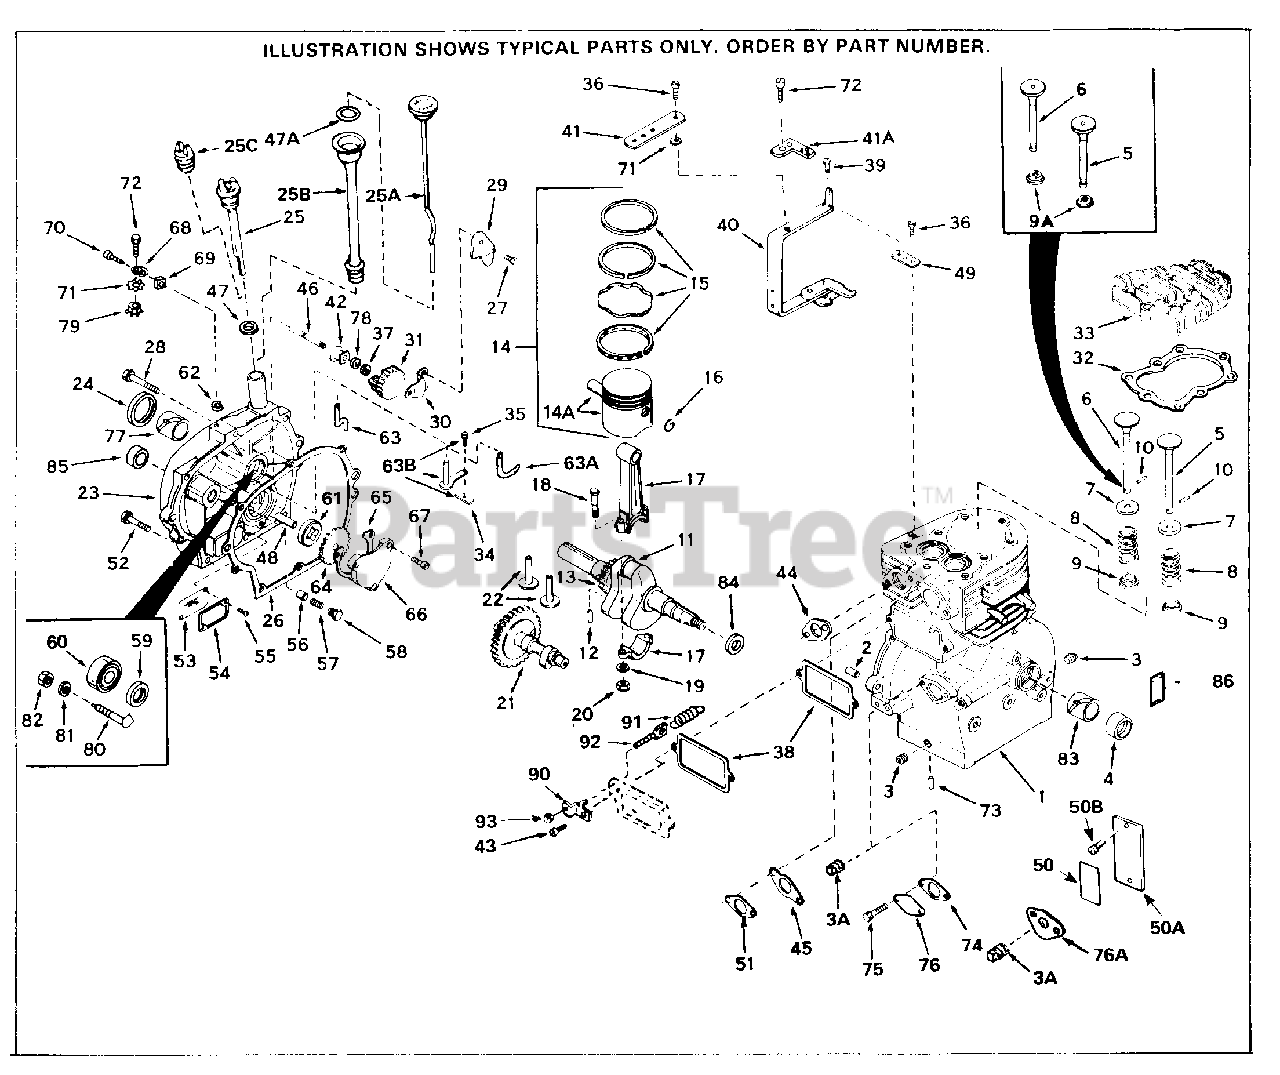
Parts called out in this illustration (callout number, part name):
1	"Cylinder (Incl. 2 thru 5 & 9A) 2-5/8 " Bore
2	Dowel Pin
3	Oil Drain Plug (Sq. hd., 1/4-18)
4	Seal, Oil
5	Intake Valve (Std.) (Incl. 9A)
5	Exhaust Valve (Std.)(Incl. 151)
5	Exhaust Valve (1/32" OS) (Incl. 151)
6	Exhaust Valve (Std.) (Incl. 9A)
6	Exhaust Valve (1/32" OS) (Incl. 9A)
6	Exhaust Valve (Std.)(Incl. 151)
6	Exhaust Valve (1/32" OS) (Incl. 151)
7	Valve Spring Cap
8	Valve Spring
9	Cap, Lower valve spring (Std.)
9	Cap, Lower valve spring (1/32" OS)
10	Pin, Valve spring retaining
11	Crankshaft NOTE: This is a crankless shortblock. Crankshaft was installe din field.
12	Pin, Crankshaft gear only)
13	Crankshaft Gear Early production onl y
14	Piston, Pin & Ring Set (Std.) 2-5/8" Bore
14	Piston, Pin & Ring Set (.010" OS)
14	Piston, Pin & Ring Set (.020" OS)
14A	Piston & Pin Ass'y. (Std.)(2-5/8") In cl. 16
14A	Piston & Pin Ass'y. (.010" OS) Incl. 16
14A	Piston & Pin Ass'y. (.020" OS) Incl. 16
15	Ring Set (Std.) (2-5/8" Bore)
15	Ring Set (.010" OS)
15	Ring Set (.020" OS)
16	Piston Pin Retaining Ring
17	Rod Assy., Connecting (Incl. 18)
18	Connecting Rod Bolt Early production
18	Bolt, Connecting rod Early production
18	Bolt, Connecting rod Late production
19	Washer ion)
20	Nut, Connecting rod Early production
21	Camshaft (MCR)
22	Lifter, Valve
23	Cover, Cylinder (Incl. 24, 46 & 77)
24	Oil Seal equired)
25	Dipstick, Oil (Incl. 47)
26	Gasket, Cylinder cover
27	Screw, 10-25 x 1/2"
28	Screw, 1/4-20 x 1-3/4"
30	Bracket, Governor gear
31	Gear Assy., Governor (Incl. 78)
32	Gasket, Cylinder head
33	Cylinder Head Not included with short block
34	Yoke, Governor
35	Screw, 6-40 x 5/16"
37	Retaining Ring
38	Valve Cover Gasket
39	Rivet, Split Used on early production
40	Governor Lever New lever does not nee d 1 of Ref. No. 39, 68, 71, 72 & 79
42	Spool, Governor
43	Screw, 10-24 x 1/2" (Use as required)
45	Intake Pipe Gasket
47	Oil Fill Plug Gasket
50	Decal, Instruction
50A	Plate, Identification Early producti on
50B	Stud, Drive (Early production)
51	Gasket, Carburetor
52	Screw, 1/4-20 x 1-1/4"
59	Washer, Thrust
60	Bearing, Ball
62	Retaining Ring
63A	Rod, Governor This one piece gov. rod is no longer used. It is replaced by 30699C assy ., Ref. No. 63B
68	Governor Lever Clamp tion)
69	Lock Nut, 10-32
70	Screw, 10-32 x 3/4"
71	Lock Washer #8
72	Screw, 8-32 x 5/16" (Use as required)
73	Pin, Dowel (Use as required)
77	Bushing, Crankshaft (Use as required)
78	Washer, Flat
79	Lock Nut, 8-32 on)
83	Bushing, Crankshaft (Use as required)
